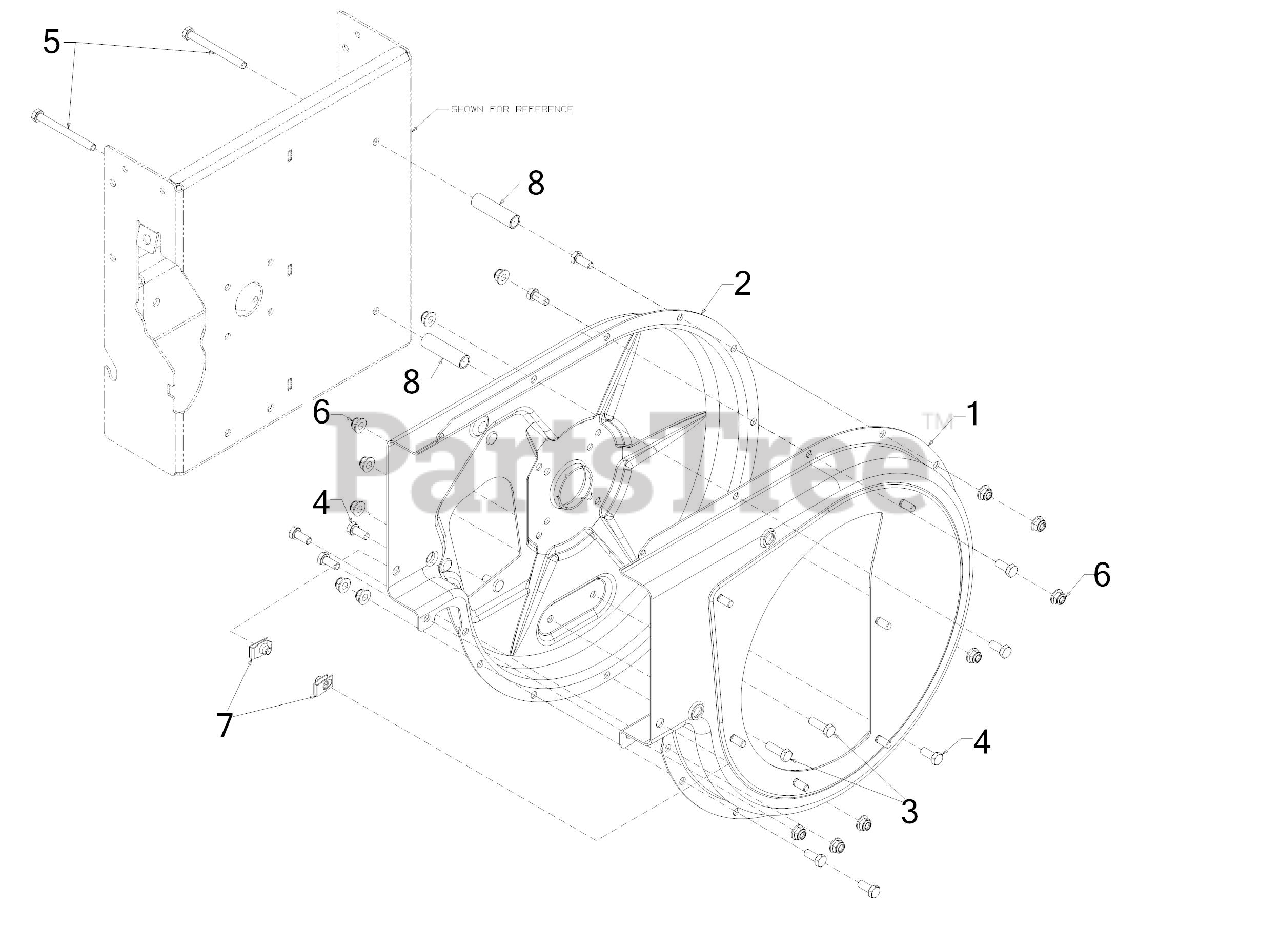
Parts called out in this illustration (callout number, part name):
1	FLAIL HOUSING ASSEMBLY (OUTER)
2	INNER FLAIL HOUSING
3	SCREW 5/16-18 x 1.0 GR5
4	SCREW 5/16-18 x .75 GR5
5	SCREW 5/16-18 x 3.25 GR5
6	FLANGE LOCK NUT 5/16-18
7	U-NUT
8	SPACER .459 X .625 X 2.31
